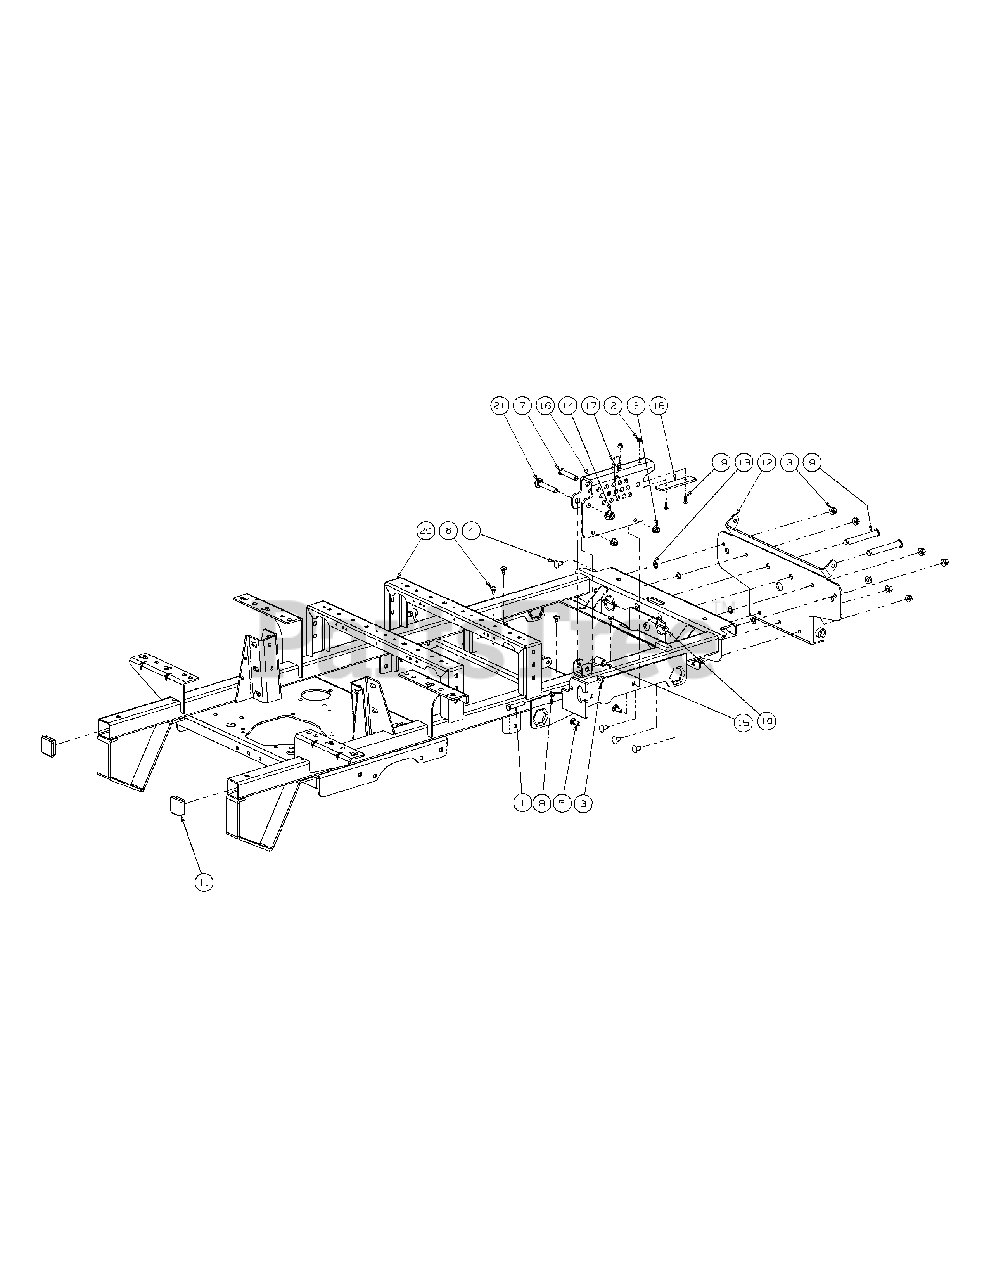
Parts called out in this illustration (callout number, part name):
1	Hex Cap Screw 3/8-16 x 2.00
2	Lock Nut w/Nylon Insert
3	Hex Nut, 3/8-16 Flange Lock
4	Carriage Bolt, 3/8-16 x .75 Long
5	Carriage Bolt, 3/8-16 x 1
6	Rubber Bumper, .62 OD x .22 Thick
7	Clevis Pin, .500 Dia. x 2.50 Lg.
8	Nut, 3/8-16, Jam
9	Clevis Pin, .625 Dia x 4.375 Long
10	Linch Pin, 3/16 Dia.
11	Plug, Square Tube
12	Bracket Assembly, Frame, Front
13	Push Retainer, 3/8
14	Nut, 1/2-13, Flangelock
15	Spacer, .51 ID x .75 OD x 1.40
16	Lift Index Bracket
17	HitchPin, .120 Dia. x 3.0
18	Wear Plate, 1.25 x 5.00
19	Flat Head Cap Screw, 1/4-20 x .75
20	Frame Assembly
21	Carriage Bolt, 1/2-13 x 3.00
